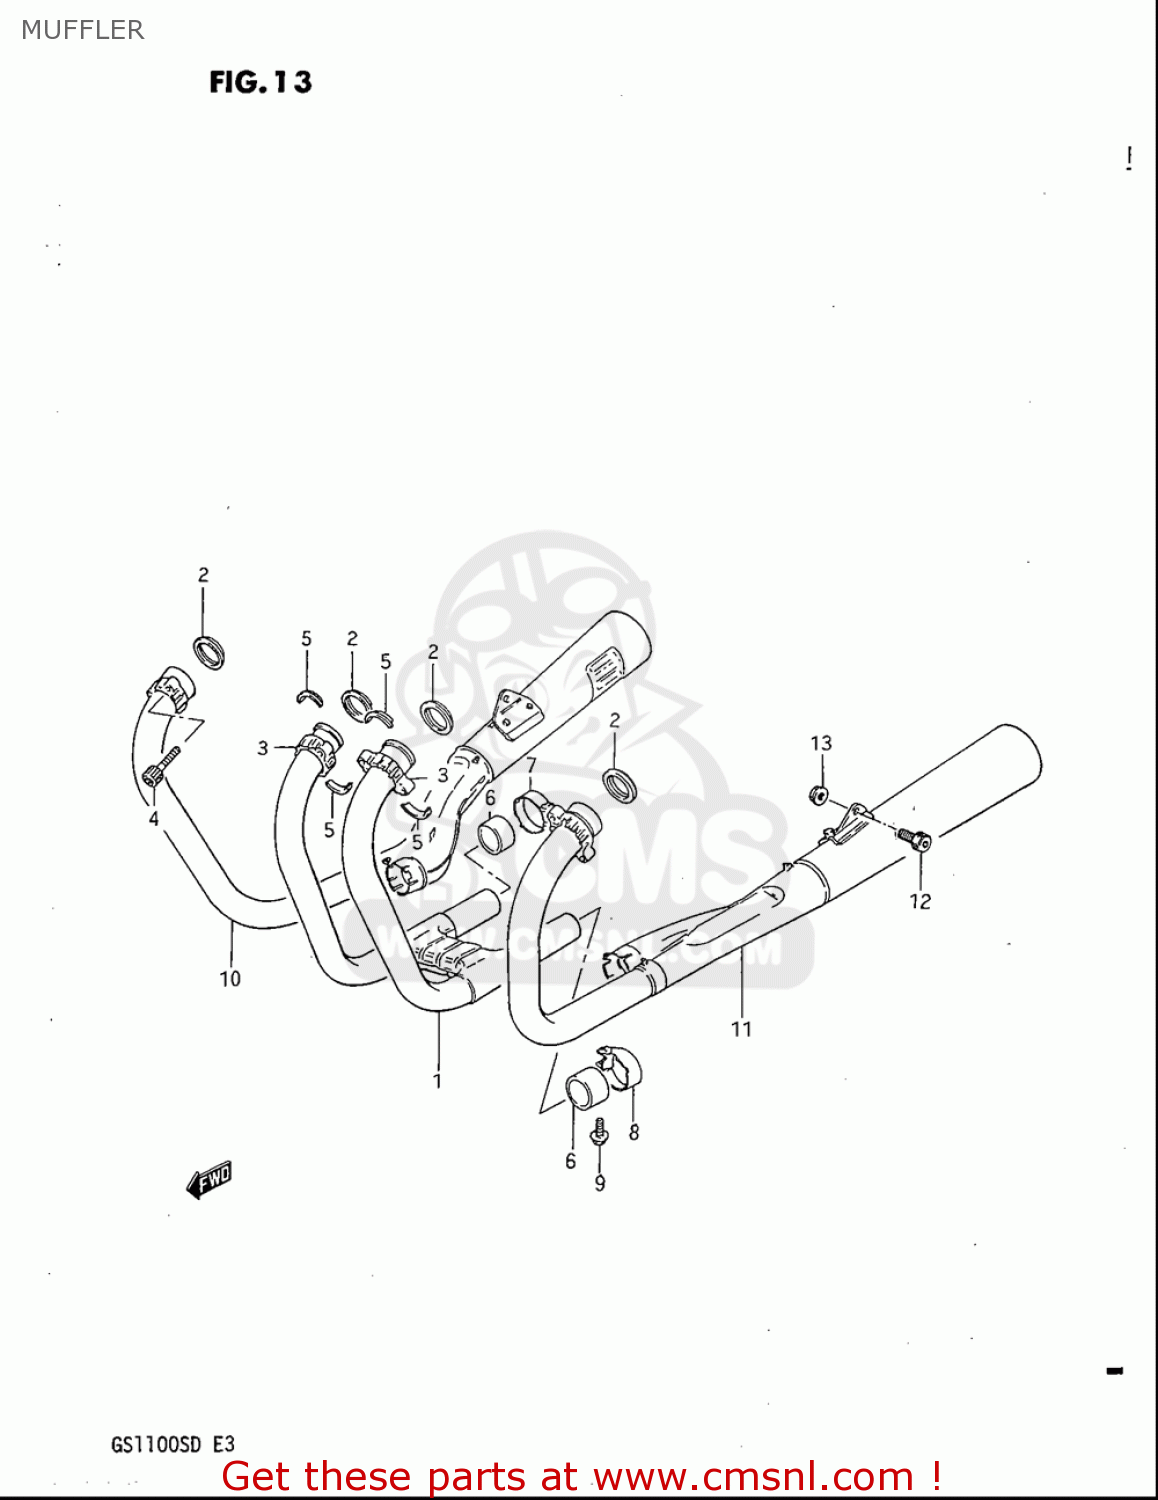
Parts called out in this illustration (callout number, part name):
1	PIPE,EXHAUST CTR
2	GASKET,EXHAUST PIPE (NAS)
4	BOLT
5	PLATE,EXHAUST P
6	CONNECTOR,MUFFLER
7	CLAMP,MUFFLER CONNECTOR,R
8	CLAMP,MUFFLER CONNECTOR,L
9	BOLT
12	BOLT
13	NUT
